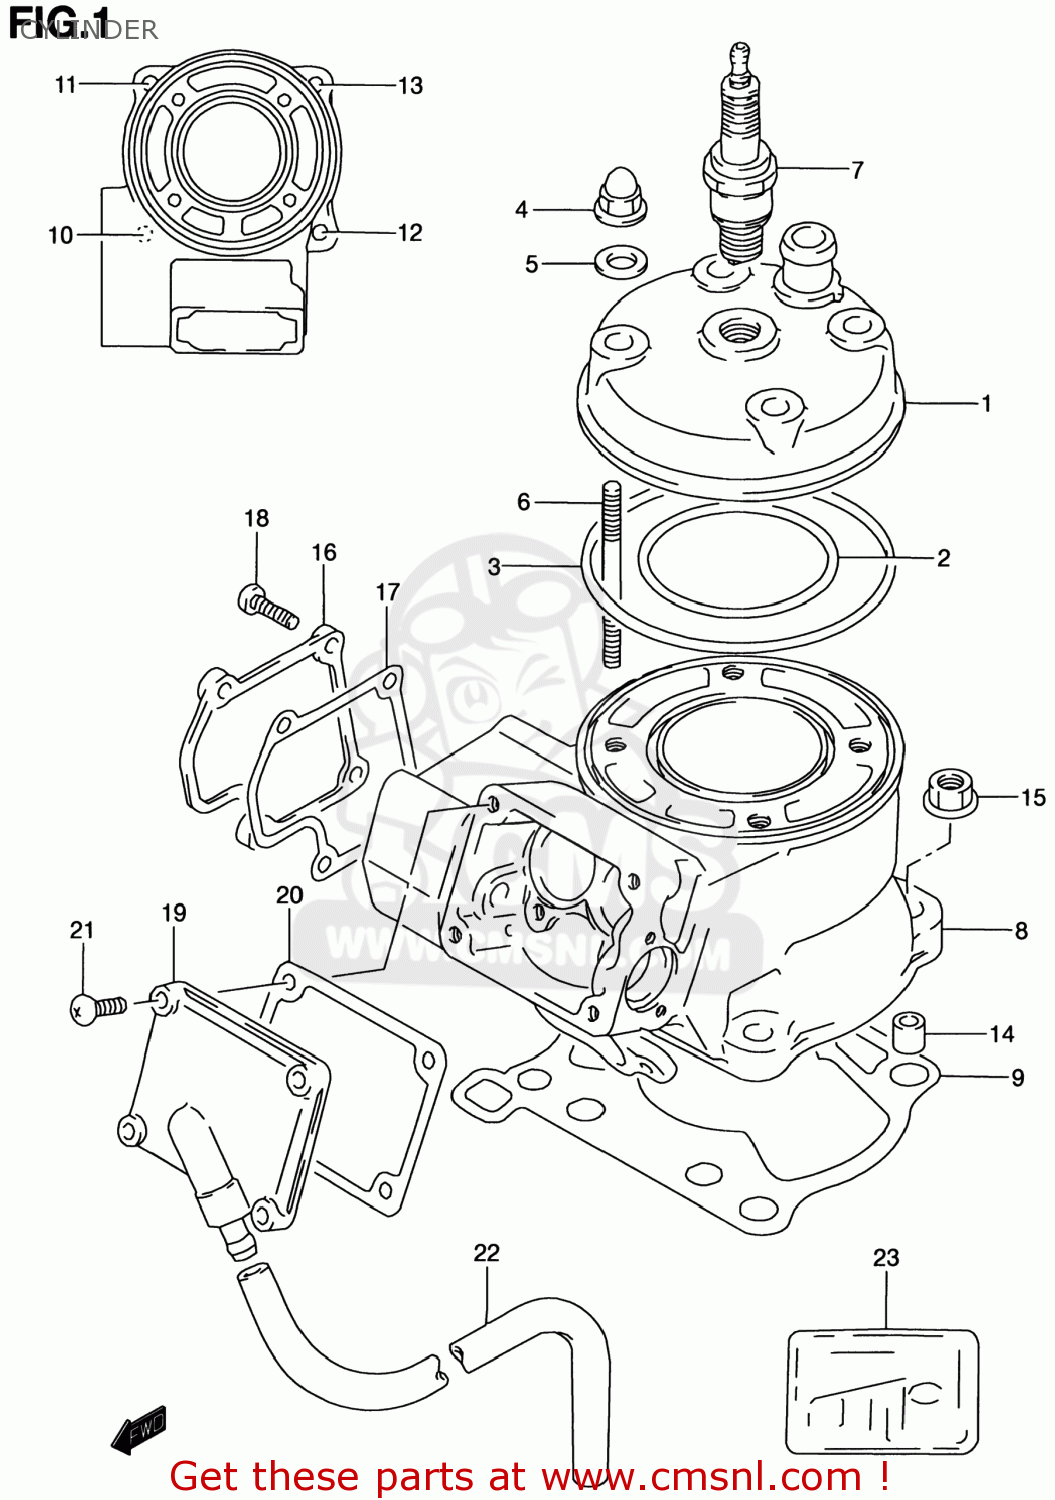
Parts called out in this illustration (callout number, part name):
1	HEAD,CYLINDER
2	O RING,CYLINDER HEAD NO.1
3	O RING,CYLINDER HEAD NO.2
4	NUT
5	GASKET(8.5X17X2.3) (NAS)
6	BOLT,STUD
7	PLUG,SPARK(BR10ES)
8	CYLINDER COMP
9	GASKET,CYLINDER (NAS)
10	BOLT,STUD
11	STUD 8X25
12	BOLT,STUD
13	STUD BOLT
14	PIN(8.4X11X14)
15	NUT
16	COVER,CYLINDER NO.1
17	GASKET,CYLINDER COVER NO.1 (NAS)
18	SCREW
19	COVER,CYLINDER
20	GASKET,CYL COVER NO.2 (NAS)
21	SCREW
22	HOSE(7X12X600)
23	GASKET SET (NAS)
